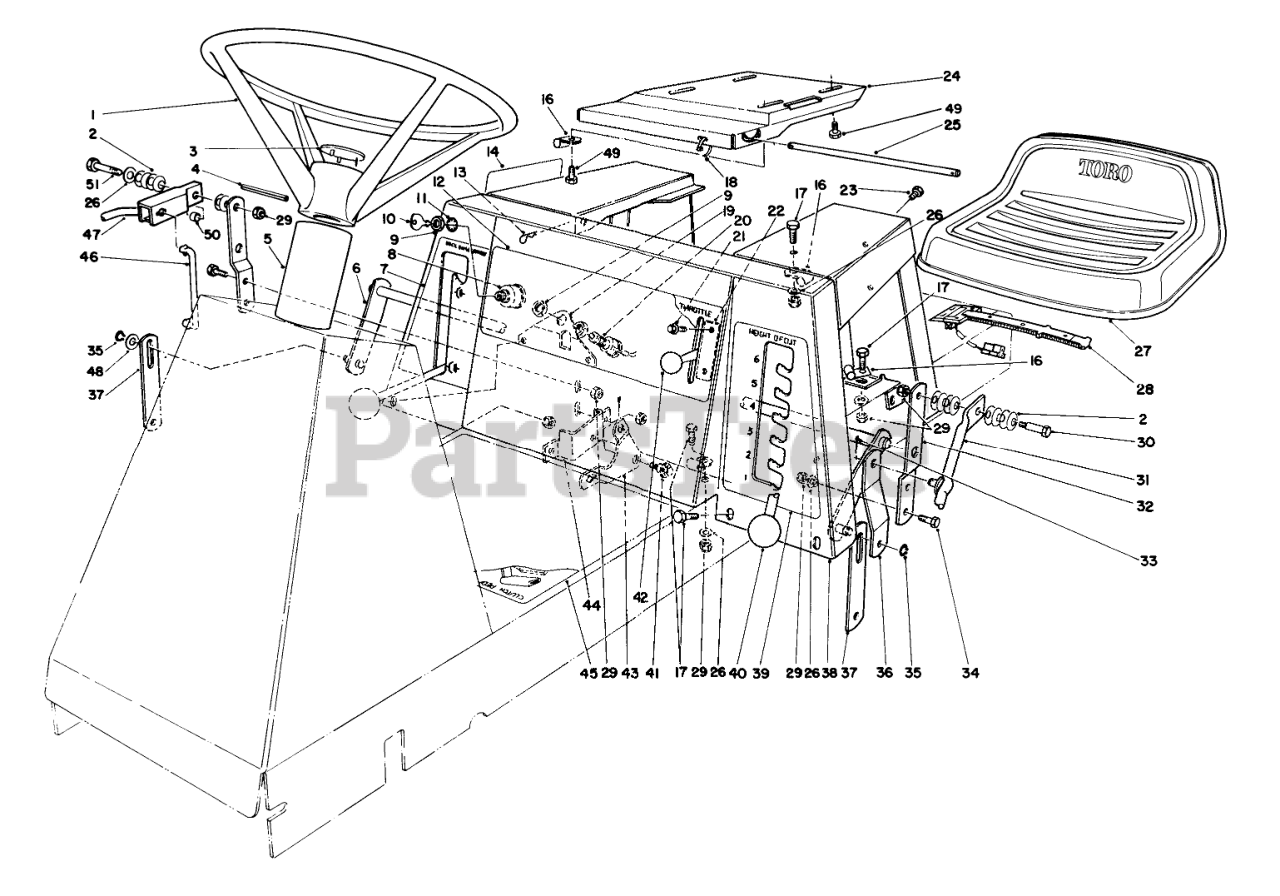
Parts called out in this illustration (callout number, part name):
1	Steering Wheel Assembly (Incl. Ref. #3)
2	WASHER-BELLEVILLE
3	Cap-Steering Wheel
4	PIN-ROLL
5	STRG. SHAFT COVER
6	Arm
7	DECK ENGAGE DECAL
8	Switch-Ignition (Incl. Ref. #9-11)
9	NUT-HH
10	Key
11	WASHER-TOOTH, INTERNAL
12	IGN & THROTTLE DECAL
13	PIN-COTTER
14	Decal Shift Pattern
16	CLAMP
17	SCREW-HH
18	TIE-CABLE
19	SWITCH MT BRKT
20	Switch-Deck (Incl. Ref. #8)
21	SCREW-HWHTF
22	Control-Throttle (Incl. Ref. #42)
23	SCREW-HH
24	SEAT BASE RO
25	SEAT BASE ROD
26	WASHER-PLAIN
27	Seat Assy. (Incl. Ref. #28)
28	SWITCH-SEAT
29	NUT-LOCK, NI
30	BOLT-SHOULDER
31	HOC LEVER WA B
32	Bracket
33	PIN-COTTER
34	SCREW-HH
35	RING-RETAINING
36	HOC ENGAGE BRKT R
37	DECK SUSP LINK B
38	Body-Seat
39	HOC DECAL
41	SCREW-SHOULDER
42	Knob
43	DECK ENGAGE BELLCRANK
44	BELLCRANK MTG BRKT
45	INSTRUCTION DECAL
46	BELLCRANK LINK(PLTD)
47	SHIFT LEVER WA B
48	WASHER-FLAT
49	SCREW-HHF
50	SPACER
51	SCREW-HH
